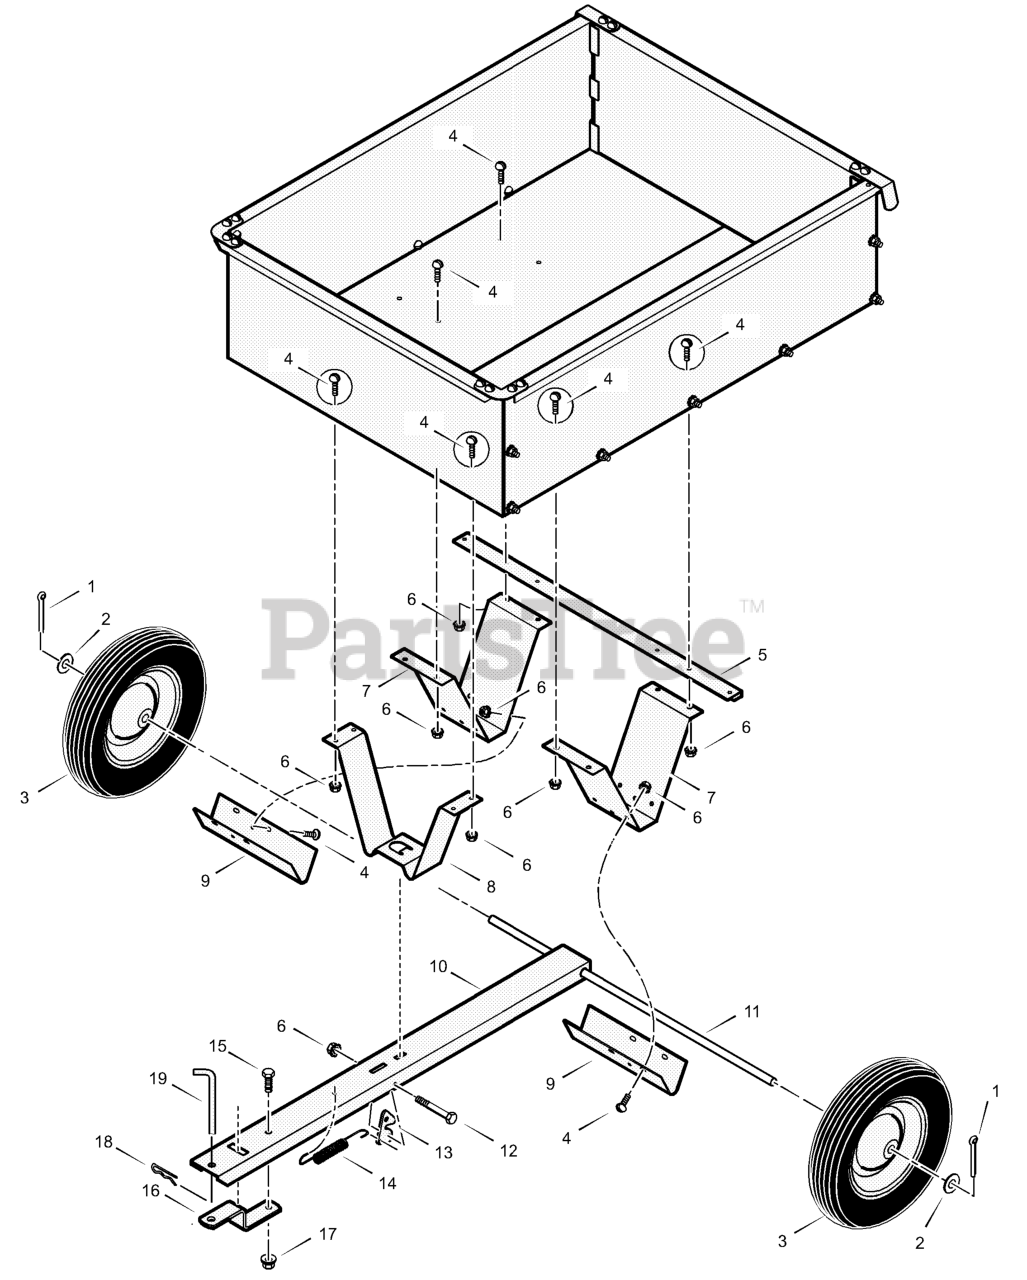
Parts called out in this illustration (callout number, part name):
1	Pin, Cotter
4	Screw 14-20x0.50
5	Support, Bottom
6	Nut, Keps 1/4-20
7	Support, Axle
8	Support, Tongue
9	Retainer, Axle
10	Tongue (Black)
12	Bolt, Hex 1/4-20x3.25
15	Bolt, Hex 3/8-16x0.75
17	Nut, Lock 3/8-16
18	Pin, Hair
19	Pin, Drawbar
